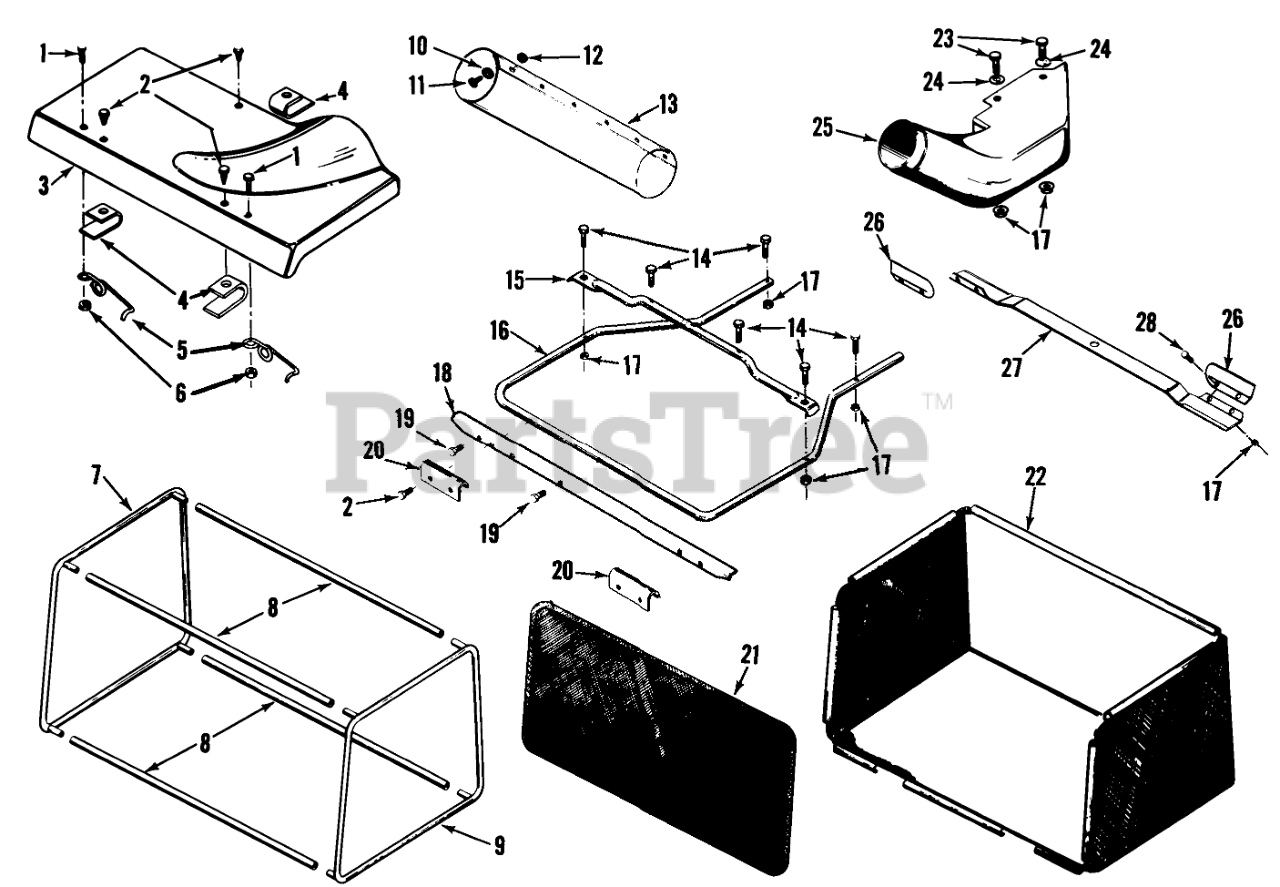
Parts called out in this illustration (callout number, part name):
1	H H C S
2	Screw, Hex Hd, Washer Slotted, No. 10-24 x 3/8 In.
3	Cover, Grass Catcher Top
4	Clip, Cover Hold Down
5	Spring, Door Hold Down
6	Nut
7	Frame Assembly, Bag, Left
8	Tube, Bag Frame
9	Frame Assembly, Bag, Right
10	WASHER
12	Nut, Centerlock Flange, No. 10-24 Thd
13	Tube, Extension
14	Bolt
15	Tube, Frame Support
16	Frame, Catcher Support
17	Nut
18	Support Angle, Catcher Bag
19	Screw
20	Bracket, Bag Hold Down
21	Door Assembly, Bag, Rear
22	Bag Assembly
23	Bolt
24	WASHER 5/16 SAE
25	Chute Extension Assembly
26	Lift Blade
27	Blade, 30 In.
28	Bolt
29	Blade Assembly Complete (Includes items 17, 26, 27 & 28)
